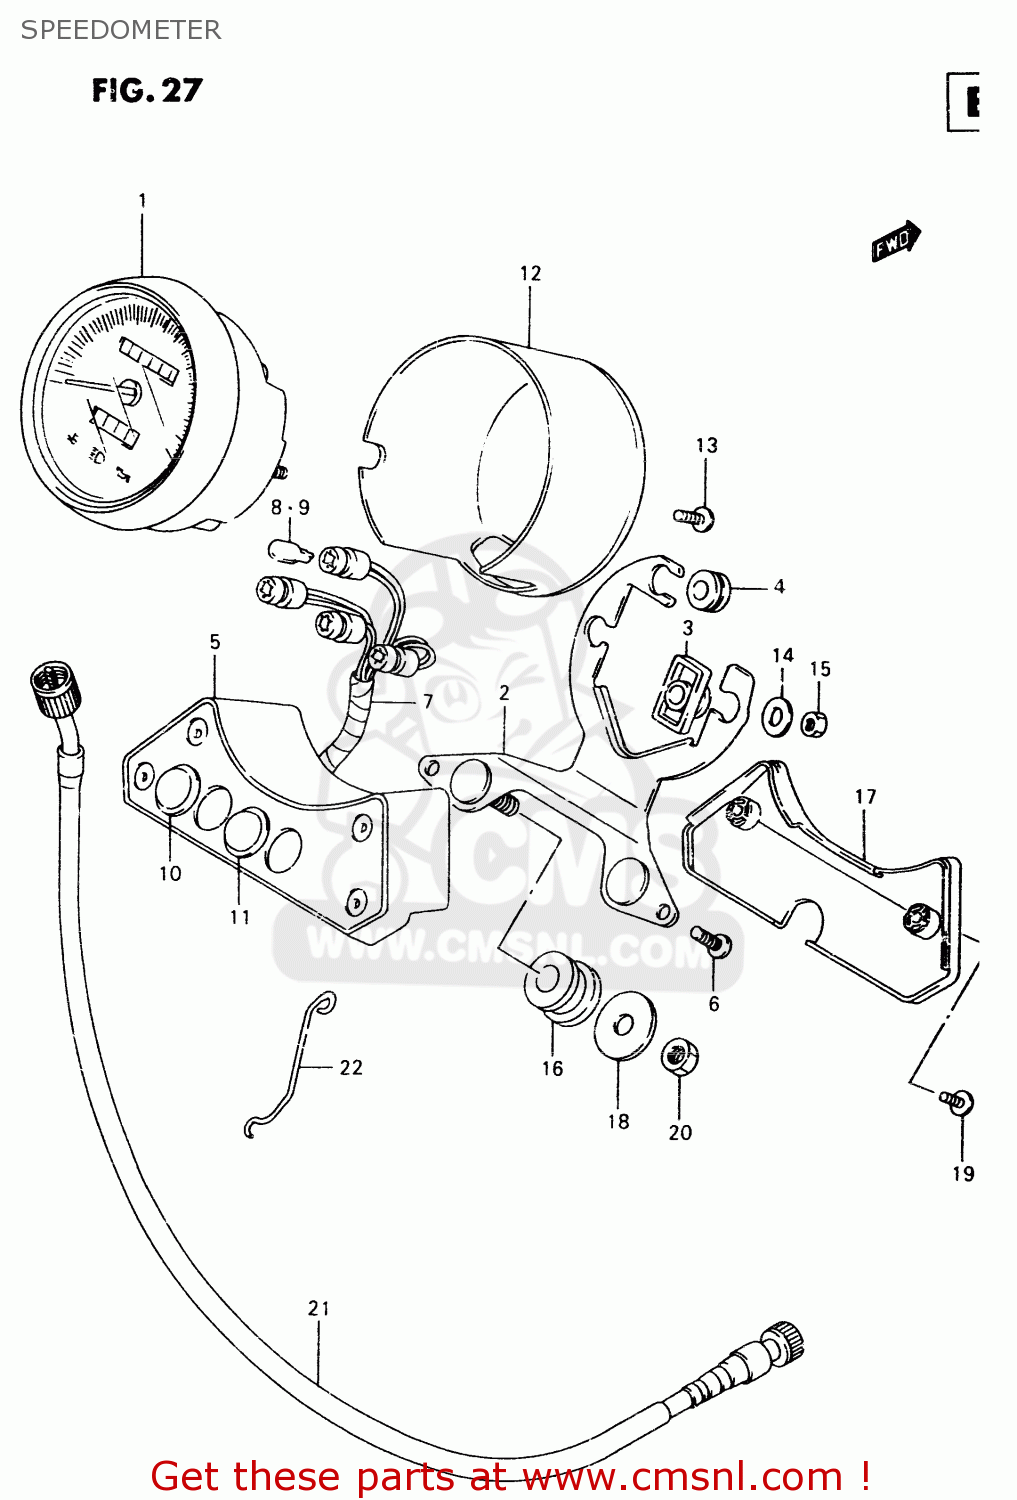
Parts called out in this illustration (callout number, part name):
1	SPEEDOMETER
2	BRACKET
3	CUSHION,DAMPER
4	DAMPER
5	CASE ASSY,PILOT
6	SCREW
7	CORD ASSY
8	BULB(12V1.7W,T6.5)
9	BULB(12V3.4W,T10)
10	LENS(GREEN)
11	LENS(GREEN)
12	COVER,UNDER(CHROMUN)
13	SCREW
14	WASHER(5.2X16X1)
15	NUT
16	CUSHION,METER BRACKET
17	COVER,P-BOX
18	WASHER(8.5X28X1.6)
19	SCREW
20	NUT
21	CABLE ASSY,SPEEDOMETER
22	GUIDE,SPEEDOMETER CABLE
